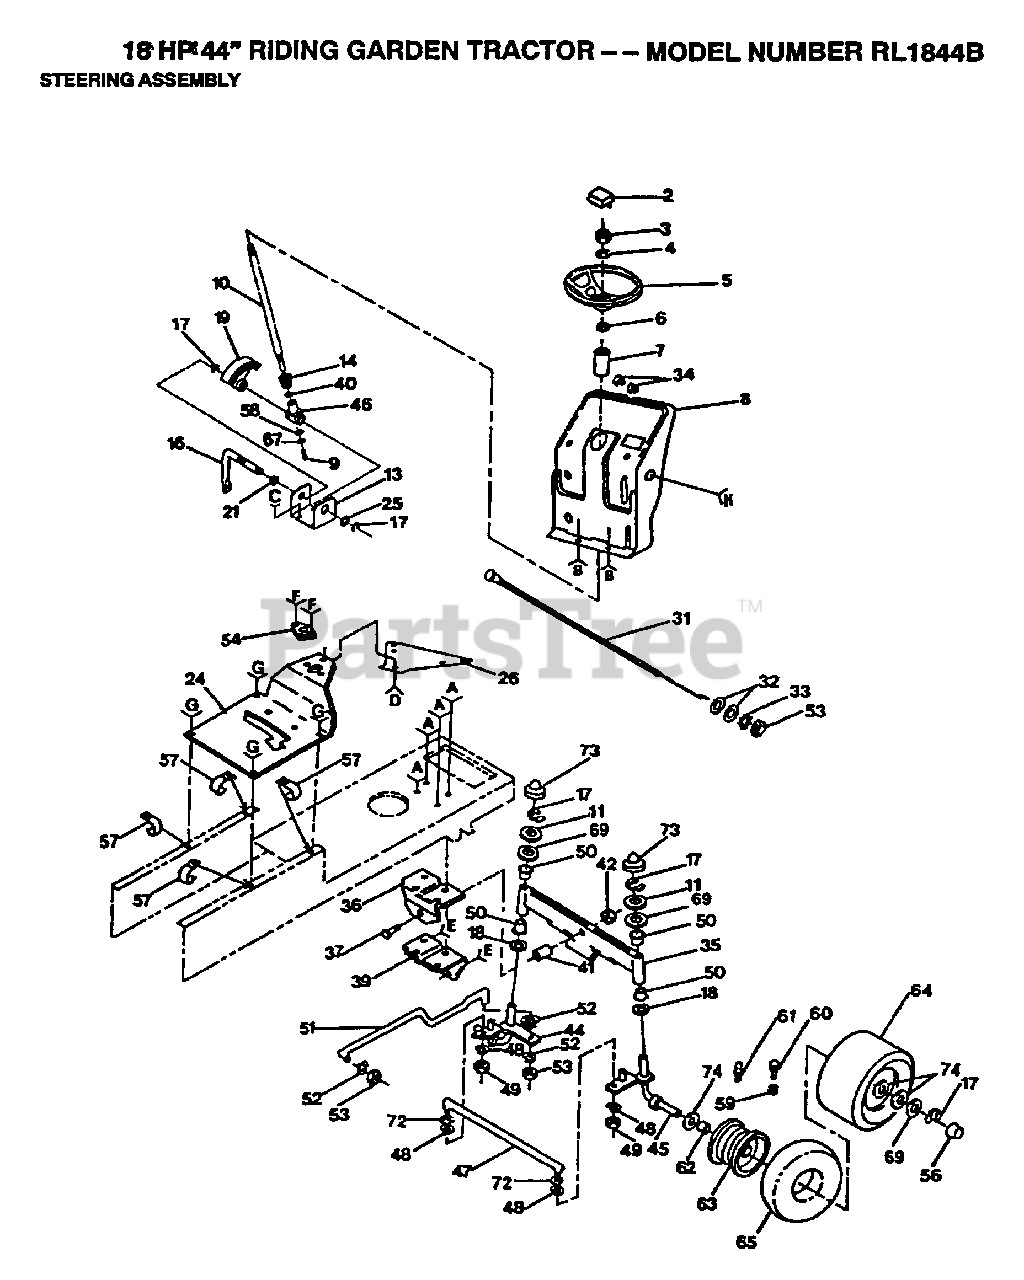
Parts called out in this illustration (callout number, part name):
2	INSERT-WHEEL LT
4	WASHER
6	ADAPTER LT
7	SLEEVE LTV
9	"SCREW,SPECIAL"
11	WASHER
13	"BRKT,STEERING"
14	"GEAR,PINION"
15	SCREW SPECIAL
17	RING
18	WASHER .T
21	NYLINER T
22	SCREW
25	WASHER .T
27	BOLT
32	WASHER
33	LOCKWASHER
34	PLUG-DASH T
35	FRONT AXLE
36	SUPPORT-SADDL T
37	BOLT LT
38	SCREW LT
39	SUPPORT.SADDLE.FT
40	THRUST WASHER
41	BEARING
42	"NUT-LOC,FLANGE LT"
43	SCREW LT
44	SPINDLE-LH LT
46	SUPPORT.SHAFT
48	LOCKWASHER
49	NUT.LOCK.5/16-24
50	COL. SRTG. BEAR.
52	LOCKWASHER
56	HUB CAP
57	CLIP T
59	VALVE CAP
60	VALVE STEM LT
61	FITTING LT
62	"FLANGE, BEARING"
65	TUBE.5.3/4.5/6
66	BOLT
67	LOCKWASHER
68	NUT
69	WASHER
70	SCREW
72	WASHER M
73	CAP
74	WASHER
